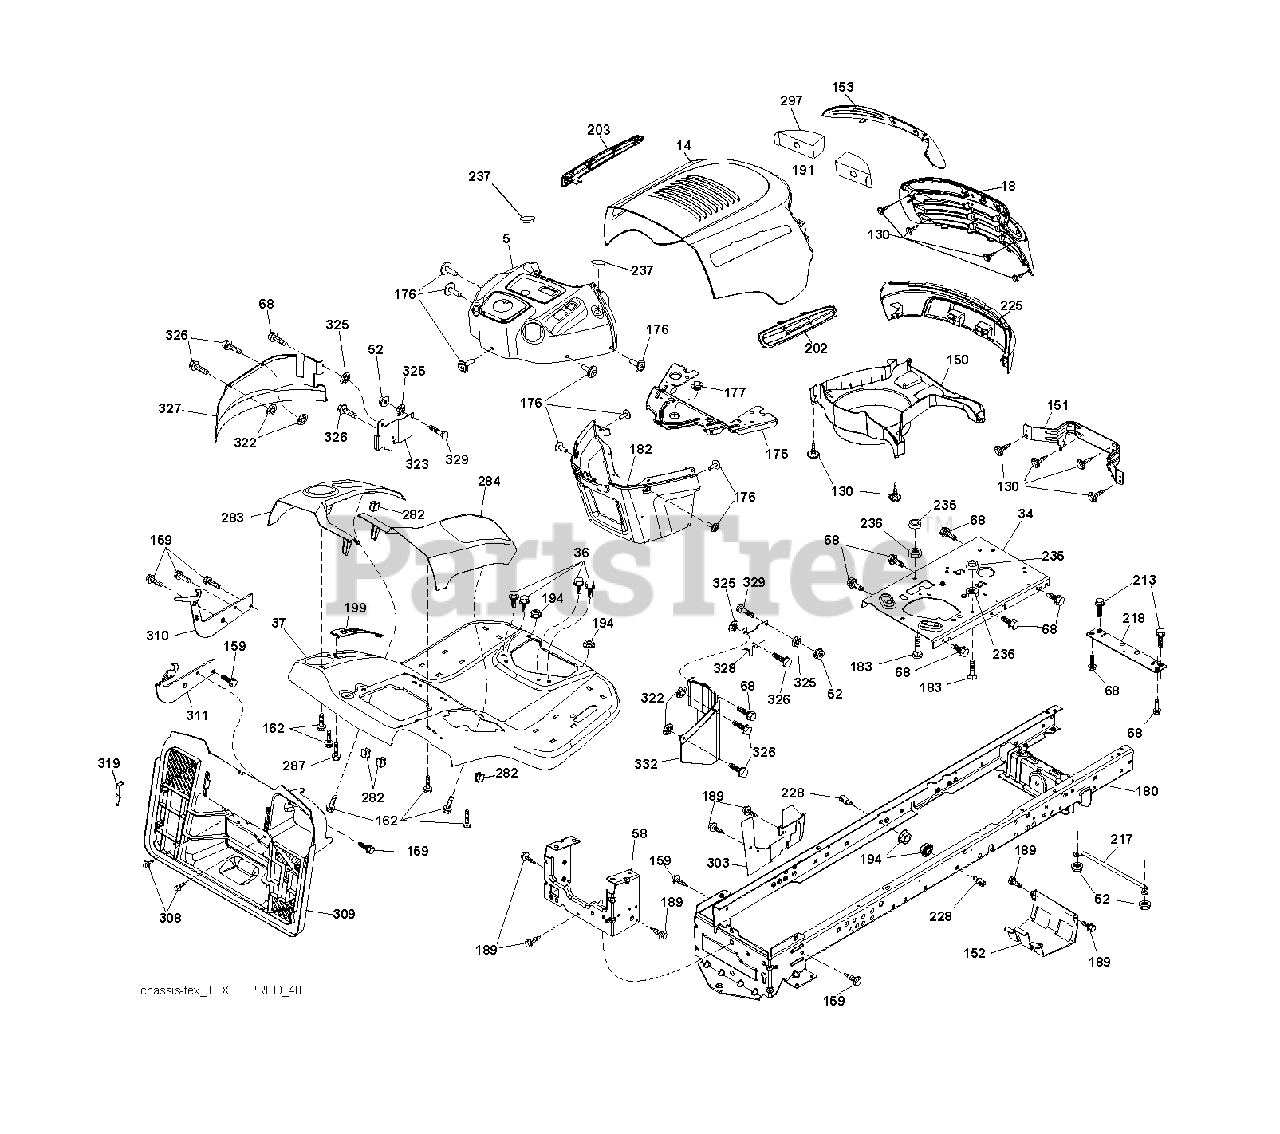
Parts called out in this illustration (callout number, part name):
34	PLATE.ENGINE.WELDED.CHASSIS
36	SCREW 5/16"
52	NUT.71038.31-18.HEX.NYLOCK
58	DRAWBAR UPPER 2PC SMALL FENDER
130	SCREW.#10 X 0.750.BOS THREAD
151	BRACKET.PIVOT.ALPHA.LT
152	SHIELD BROWNING
159	SCREW, 3/8-16X3/4
162	SCREW.HI-LO.CONSOLE
175	CROSSMEMBER
176	SCREW.#10-24X5/8.RN.QU
177	BUSHING STEERING
182	DASH.LWER.PREDATOR/HUSQ.LT
183	BOLT.5/16-18X1-1/4 FULL THD
189	SCREW
191	INSERT.REFLECT.PREDATOR.LT.RH
194	NUT LOCK HEX FLANGE 5/16-18
213	BOLT
217	ROD.PIVOT.HOOD
218	X-PIECE.HOOD.STOP.NON/
228	STUD.FASTNER.W/ANTI-ROTATE
235	SPACER FENDER
236	NUT.CENTERLOCK.5/16-
237	PLUG.MOUNT.CARGO.BLK
282	CLIP.RETAINER.CONSOLE.LT.HUSQ
297	REFLECTOR.INSERT.PRED.LH.LT
308	BOLT, 5/16-18 X 1 3/4
322	PALNUT 1/4
326	SCREW 14-20 X 5/8
329	BOLT
